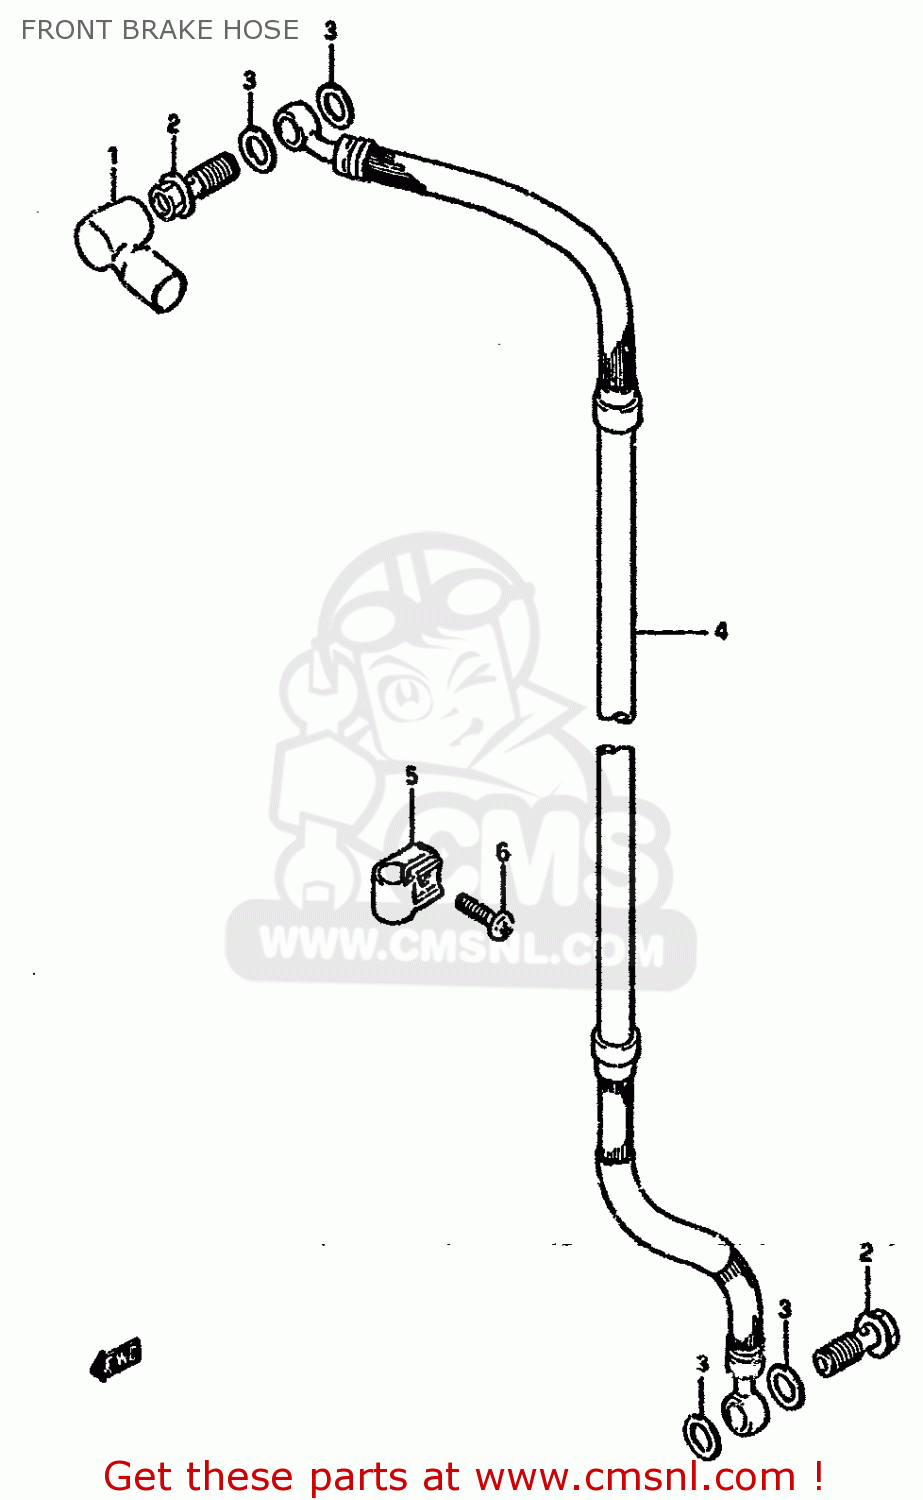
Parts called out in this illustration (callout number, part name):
1	BOOT,MASTER CYLINDER
2	BOLT UNION
3	WASHER(10X15X1.5)
4	HOSE,FRONT BRAKE
5	CLAMP,BRAKE HOSE
6	SCREW
